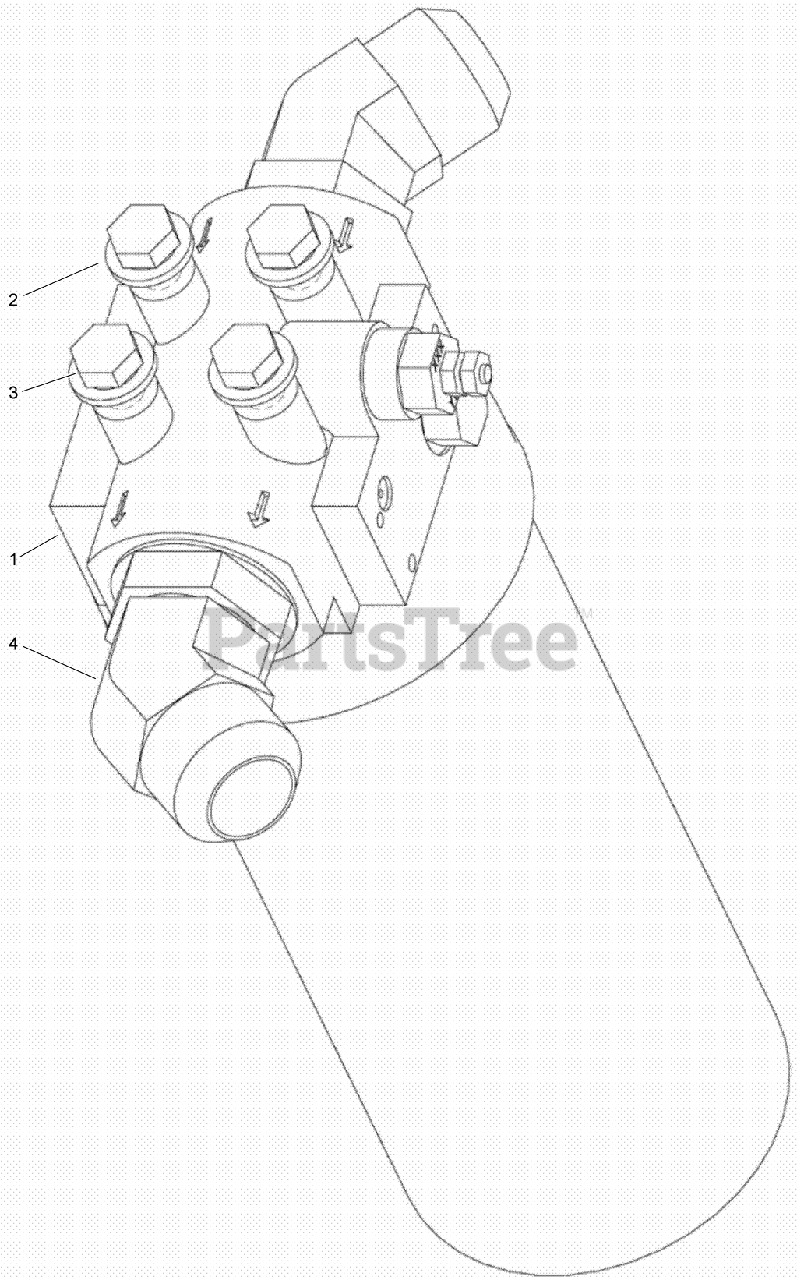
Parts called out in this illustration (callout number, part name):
1	OIL FILTER ASM
2	WASHER-FLAT
3	SCREW-HH
4	FITTING-ELBOW, 45
